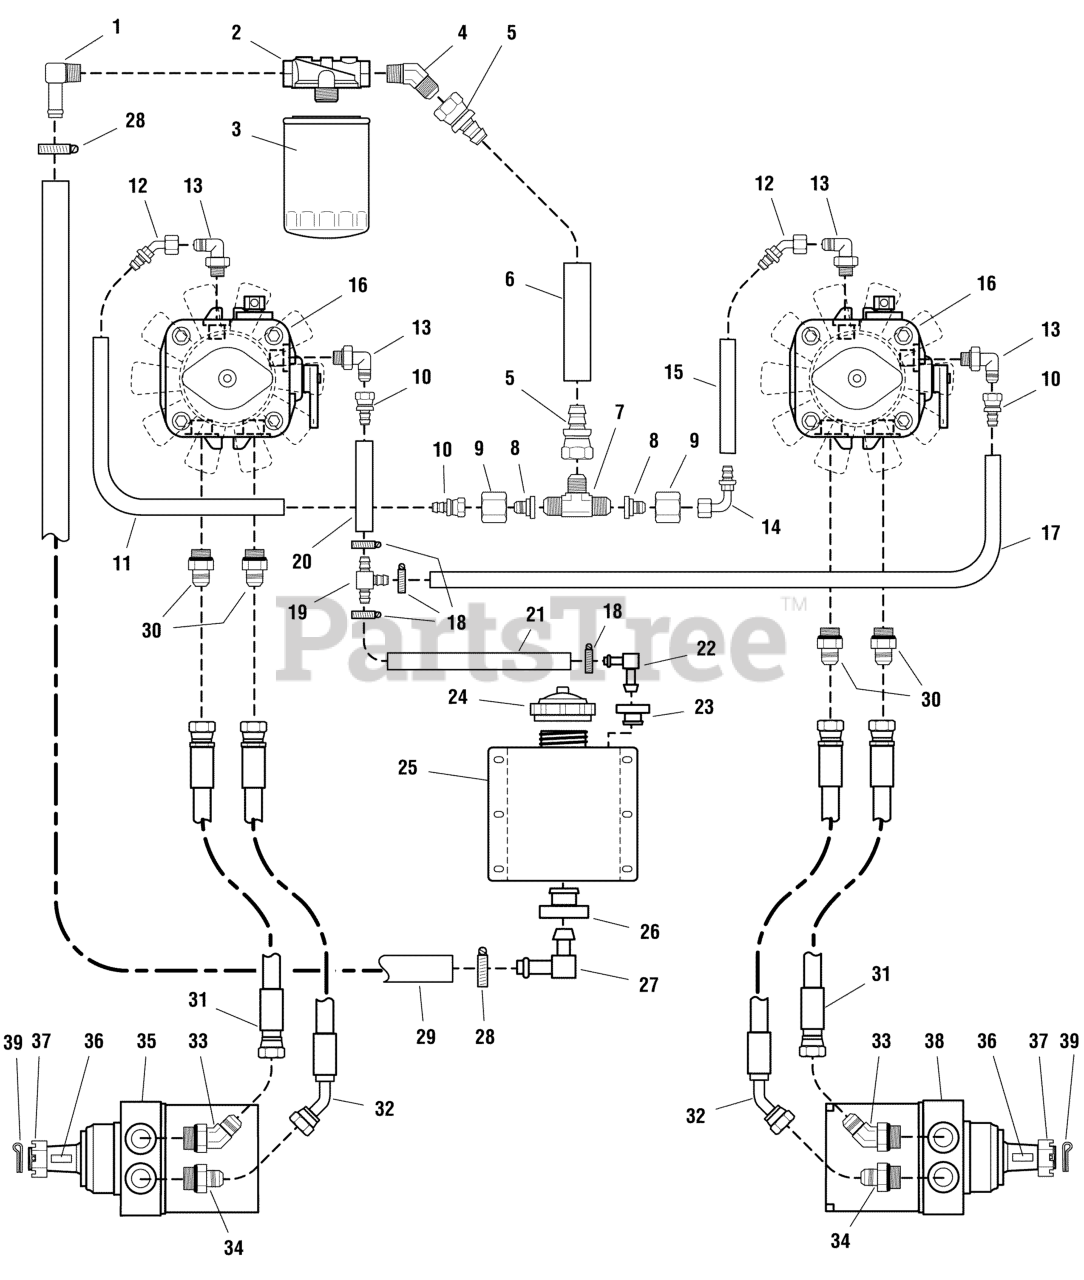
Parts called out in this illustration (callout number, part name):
1	FITTING, 1/2" NPT, 90 Deg.
2	FILTER HEAD
3	FILTER, HYDRAULIC, SERVICE PART (PKG)
4	FITTING, 1/2" NPT, 45 Deg.
5	FITTING, Straight Swivel
6	HOSE, Hydraulic, 7-1/2"
7	FITTING, Tee
8	ADAPTER, Tee
9	NUT, Adapter
10	FITTING, Straight Swivel
11	HOSE, Hydraulic, 13-3/4"
12	FITTING, 45 Deg. Swivel
13	FITTING, O-Ring, 90 Deg.
14	FITTING, 90 Deg. Swivel
15	HOSE, Hydraulic, 6-3/4"
16	HYDRAULIC PUMP, 10CC, w/ FAN
17	HOSE, Hydraulic, 16-1/2"
18	CLAMP, #6 Hose
19	FITTING, TEE, 3/8" Hose
20	HOSE, Hydraulic, 6"
21	HOSE, Hydraulic, 17-1/2"
22	FITTING, Elbow, 3/8"
23	GROMMET
24	CAP, Hydraulic Oil Only
25	HYDRAULIC OIL RESERVOIR, Complete
26	GROMMET
27	FITTING, Elbow, 5/8"
28	CLAMP, #10 Hose
29	HOSE, Hydraulic, 18"
30	FITTING, O-Ring Adapter
31	HOSE ASSEMBLY, (21), HP, ST X ST
32	HYDRAULIC HOSE ASSEMBLY, 25"
33	FITTING, O-Ring, 45 Deg.
34	FITTING, O-Ring Adapter
35	HYDRAULIC WHEEL MOTOR-LEFT, Complete
36	KEY
37	NUT, CASTLE, 1-20
38	HYDRAULIC WHEEL MOTOR-RIGHT, Complete
39	PIN, COTTER, 1/8" X 2"
